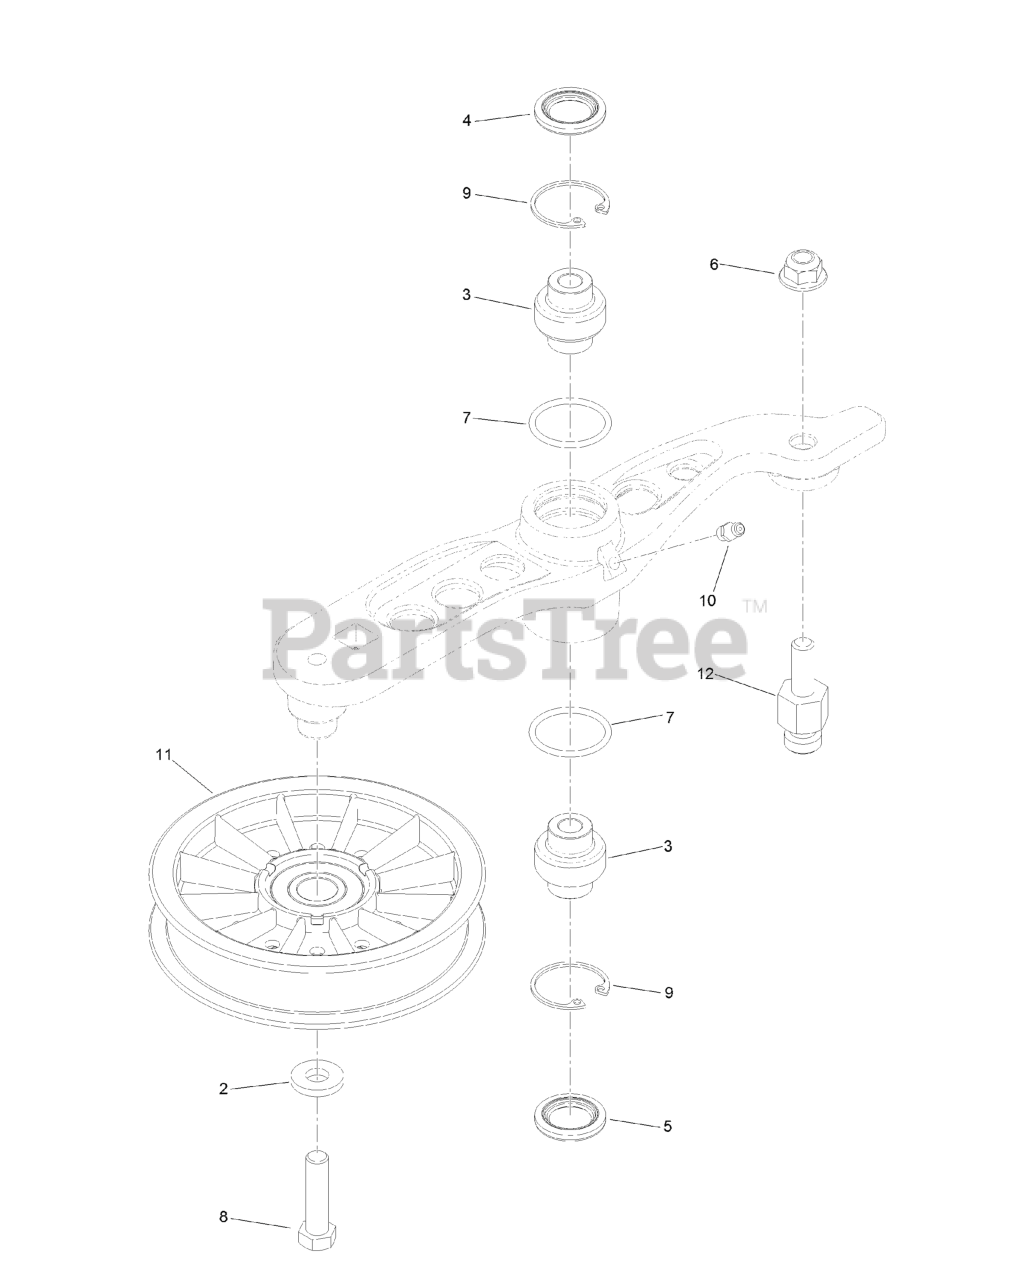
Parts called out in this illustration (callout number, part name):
3	BEARING-SPHERICAL
4	SEAL-LIP, DOUBLE
5	SEAL-LIP, SINGLE
6	Nut-Nyloc 3/8-16 Flg
8	SCREW-HH
9	RING-SNAP
10	FITTING-GREASE
11	PULLEY-IDLER
12	PIN-ANCHOR, SPRING
